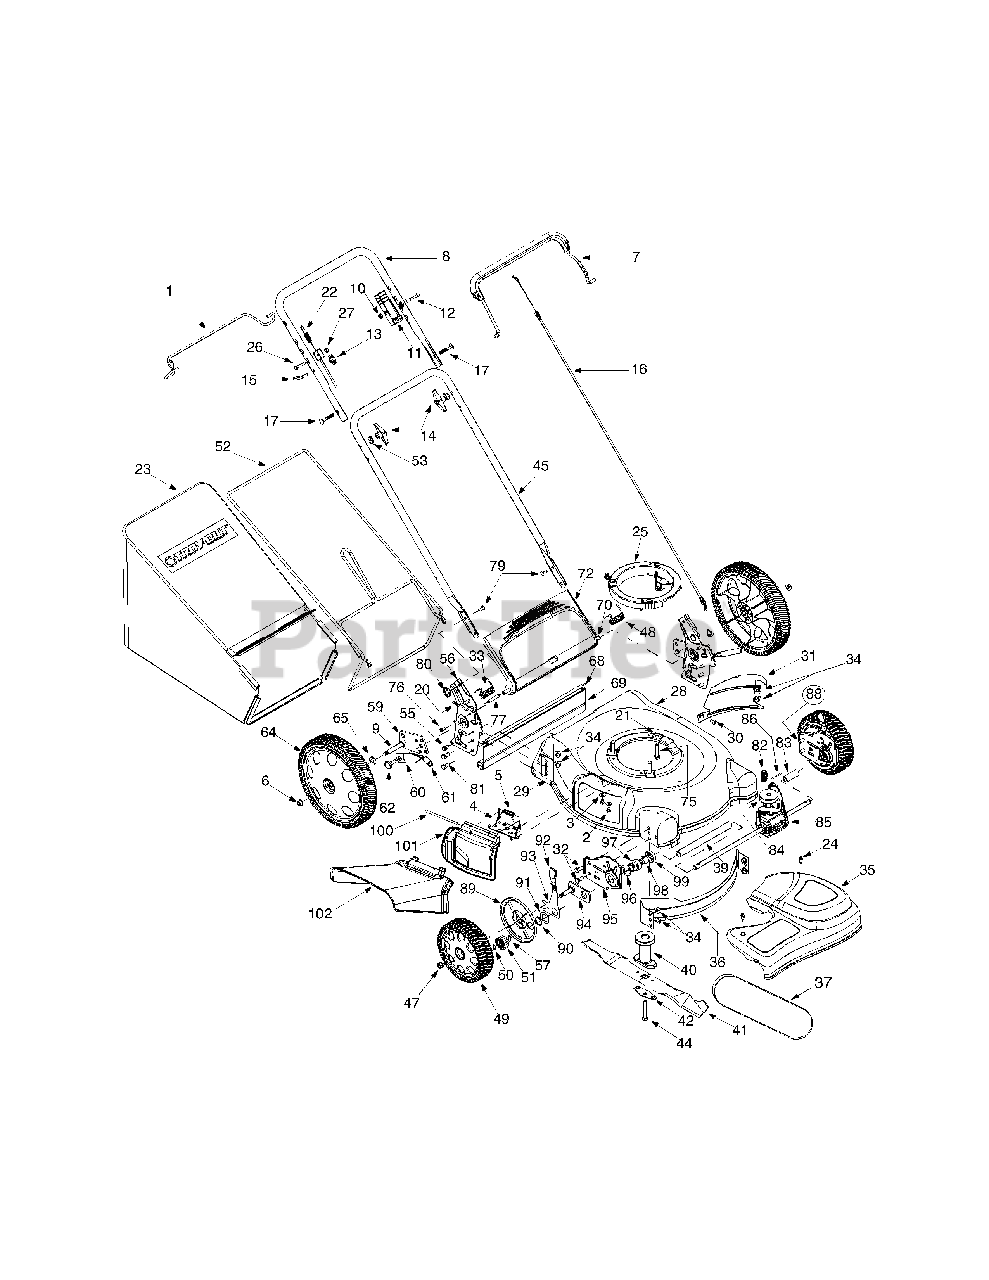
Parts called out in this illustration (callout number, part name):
1	Lower Bail Handle
2	TT Screw 1/4-20 x 0.5
3	Bell Washer .265 x 0.75
5	Torsion Spring
6	Lock Nut
7	Control Lever
8	Upper Handle
9	Axle: Rear
10	Hex Lock Nut, 1/4-20
11	Throttle Housing
12	Oval C-Sunk Screw 1/4-20 x 1.31
13	Handle Knob
14	Handle Knob
16	Control Cable: 40.5"
17	Carriage Bolt 5/16-18 x 2.0
18	RH Bracket Assembly
18	LH Bracket Assembly
20	Cotter Pin
21	Self-Tapping Sems Screw
22	Drive Cable
23	Grassbag Assembly
24	Shoulder Screw # 12 -24
25	Engine Spacer
26	Hex Bolt 1/4-20 x 1.5
27	Lock Nut 1/4-20
29	RH Rear Baffle
30	Screw AB: 1/4-14: .625
31	LH Rear Baffle
32	Hex Screw 3/8-16 x .75
33	Torsion Spring
34	Hex Nut 3/8-16
35	Transmission Cover (Black)
36	Front Baffle
38	Hex Nut 1/4-20
39	Sleeve Spacer 10.1" Lg.
40	Blade Adapter w/ Pulley
41	21" Mulching Blade
42	Blade Bell Support
43	Hex Screw 1/4-20 x 1.50
44	Hex Screw 3/8-24 x 2.50
47	Flange Lock Nut
48	Torsion Spring
49	Wheel 8 x 2.125
50	Snap Ring
51	Gear 14T LH FWD
52	Grass Bag Frame
53	Saddle Washer
54	Hex Flange Lock Nut 3/8-16
55	Hex Scr. w/Washer 1/4-14 x .625
56	RH Handle Bracket
56	LH Handle Bracket
57	Dowel Pin
58	Pan Head Screw
59	Pivot Bar
60	Height Adj. Lever
61	Foam Grip
62	Shoulder Scr .500 Dia. x .434
63	Washer .401 x .870 x .063
64	Wheel, 14 x 2.125
65	Spring Washer .50 I.D. x 1.0 O.D.
66	Flat Washer
67	Shoulder Screw
68	Wire
69	Rear Trailing Shield
70	Pivot Rod
71	Torsion Spring
72	Rear Discharge Door
75	Shoulder Screw
76	Machine Screw
77	Spacer .375 x .50 x 1.02" Lg.
78	Shoulder Screw 1/4-14
79	Carriage Bolt 1/4-20
80	Wing Nut
81	Hex Bolt 3/8-16 x 1.0"
82	Belt Tension Spring
83	Slev. Spacer 2.1" Lg.
84	Input Pulley
85	Transmission Assembly
88	Height Adjustment Assembly RH
89	Wheel Dust Cap
90	Snap Ring
92	Adjustment Knob
93	Front Lever RH
94	Pivot Plate Assembly
95	Height Adj. Plate RH
96	Wave Washer
97	Bearing Support
98	Bearing Sleeve
99	Bearing Retainer
100	Hinge Pin
101	Mulch Plug Comp.
102	Chute Deflector
